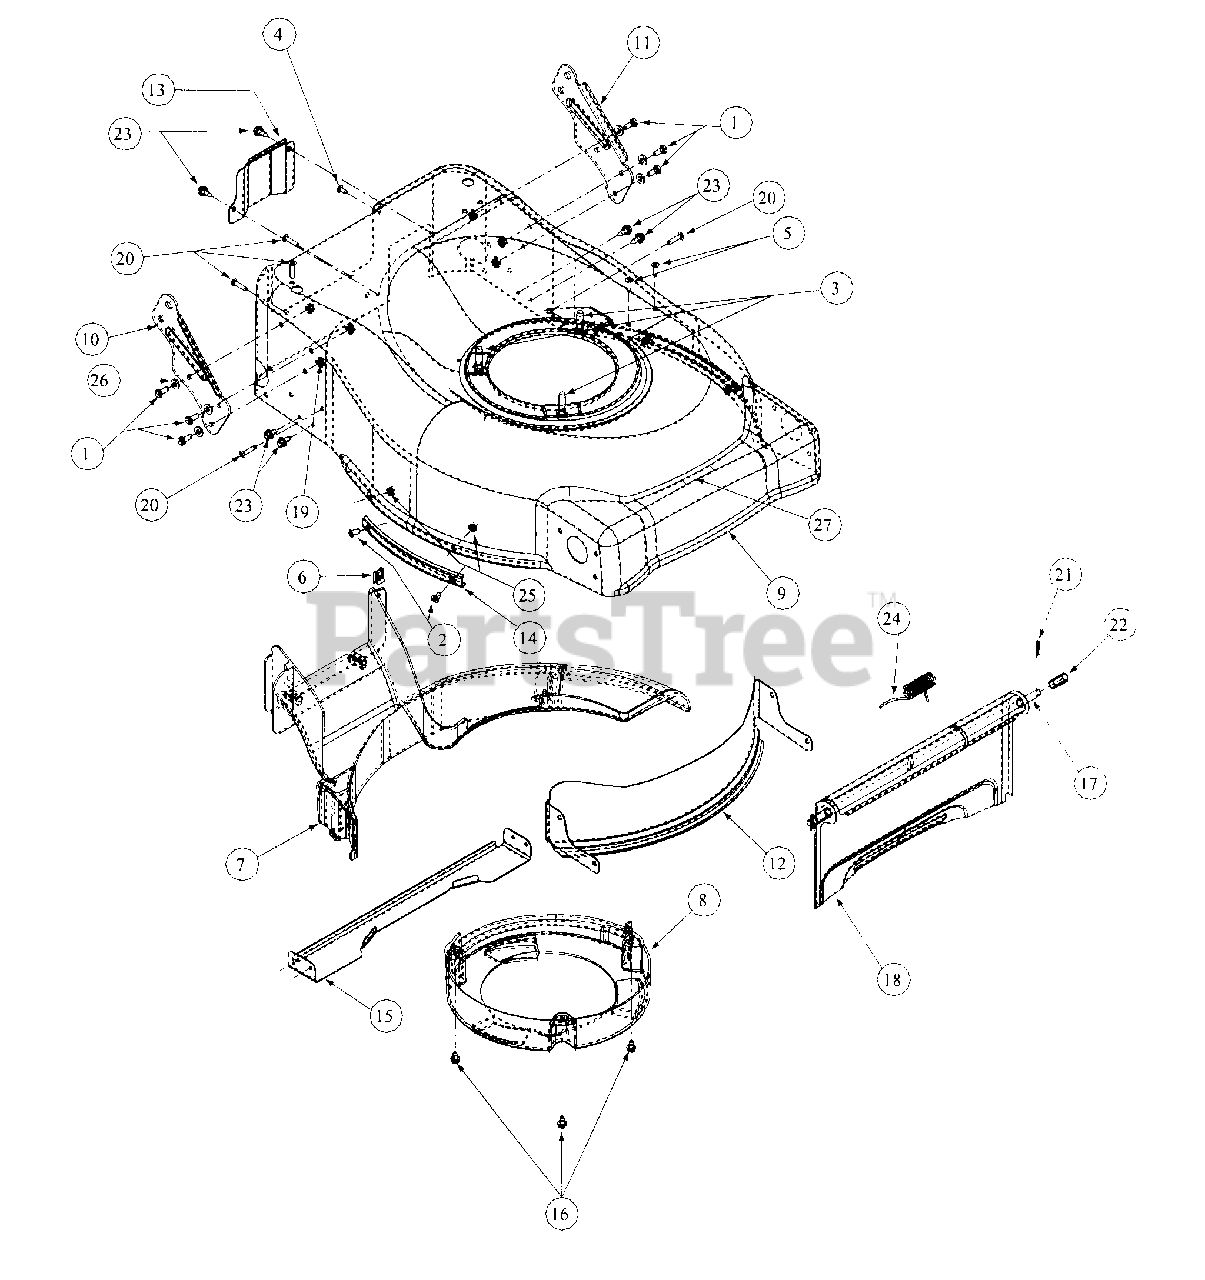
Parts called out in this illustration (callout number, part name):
1	HHCS, 1/4-20, .620, GR5, Standard
2	Screw Button HD, 1/4-20 x .5
3	Screw, TTSems, 3/8-16, 1.250, HXLWS
4	Screw, B, 10-16, 0.500, TRUSTRX1
5	Screw, HL, 12-16:0.750, TRUSTRX1
6	U-Nut, 10-16
7	Baffle, RR, 21" Commercial
8	Cover, 21" Commercial
9	Deck, 21" Commercial
10	Bracket, Handle, RH Commercial
11	Bracket, Handle, LH Commercial
12	Baffle Front Commercial 10.81 R
13	Cover Plate
14	Guard, Deck Side Flange
15	Bracket, Support Baffle
16	Screw, TT, 1/4-20, 0.375, Hex Indicator Washer
17	Rod, Pivot, Chute Door, .375 D1
18	Door, Grassbag, 21" RB
19	Nut, 1/4-20, Hex Flange, Lock Group F
20	Screw, HL, 12-16, 1.000, TRUSTRXI
21	Cotter Pin, INT .072 x 1.12 LG
22	Spacer, .375 x .50 x 1.02 LG
23	Screw, AB, 1/4-14, 0.625, Hex Indicator Washer
24	Spacer, Torsion, LH 0.120 x 15C
25	Hex Nut, 1/4-20
26	Flat Washer, 1/4 x .630 x x .0515
27	Label 21" Commercial
